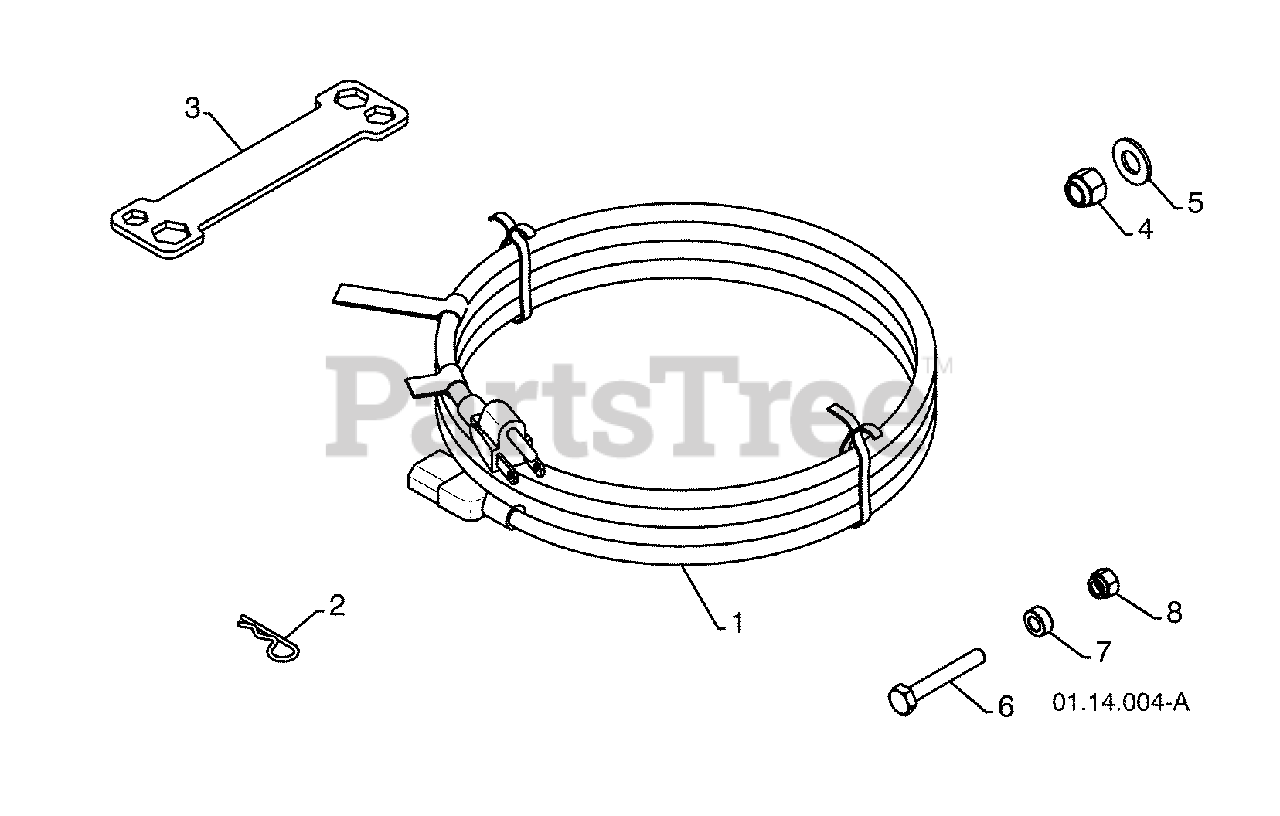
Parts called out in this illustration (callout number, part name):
1	POWER CORD
2	RETAINER PIN
3	WRENCH
4	LOCKNUT 3/8-16
5	WASHER 3/8
6	SHEAR BOLT 1/4-20 X 1-3/4
8	LOCKNUT 1/4-20
